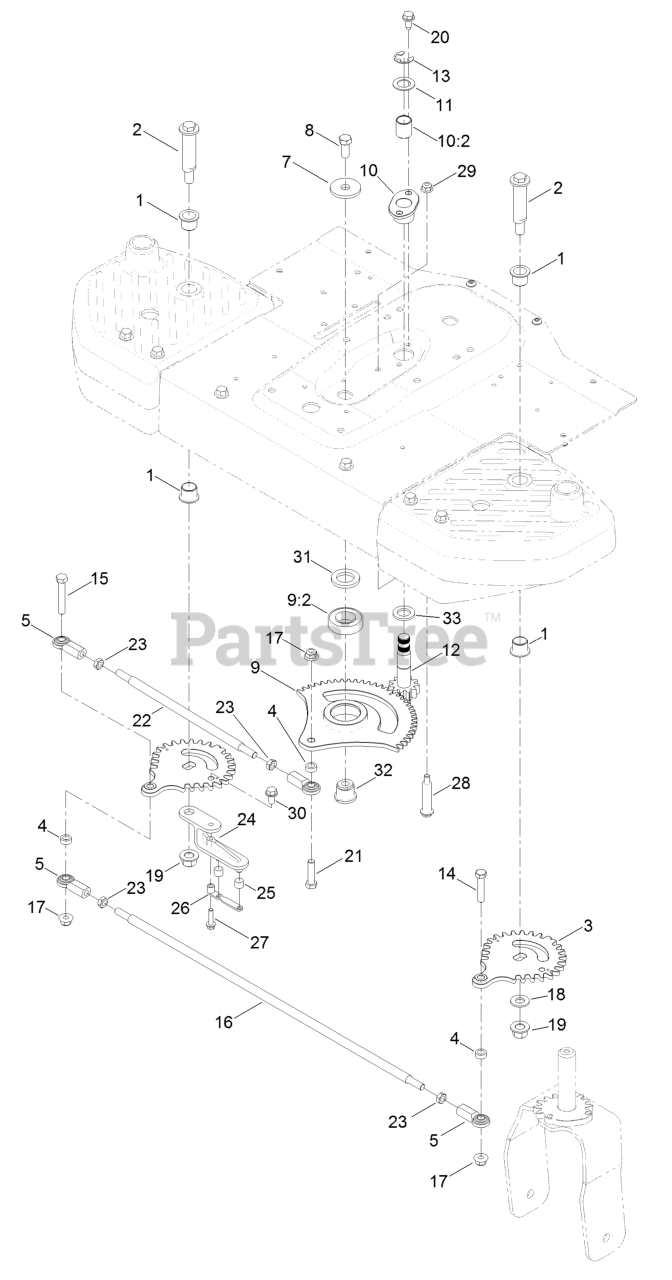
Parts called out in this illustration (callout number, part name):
1	BEARING-FLANGE, IGLIDE
2	BOLT-SHOULDER
3	GEAR-WHEEL, 30 TOOTH
5	JOINT-BALL, END
7	WASHER-THRUST
8	SCREW-HH
9	SECTOR GEAR ASM
9:2	BEARING-BALL
10	FLANGE BEARING ASM
10:2	BUSHING-STRAIGHT
11	WASHER-THRUST
12	LOWER STEERING SHAFT ASM
14	SCREW-HH
15	SCREW-HH
16	ROD-CROSS, WIDE
17	NUT-HF, NI
18	WASHER-FLAT
19	Nut-Lock 1/2-13
20	Screw-HWH 5/16-18 X 3/4 Tf
21	SCREW-HH
22	ROD-STEERING, WIDE
23	NUT-HJ
24	LEVER-CABLE
25	BUSHING
26	STRAP-ROLLER
27	SCREW-HWHTF
28	BOLT-SHOULDER
29	NUT-HF, NI
30	SCREW-HWHTF
31	SPACER-BEARING
32	PIVOT-BEARING
